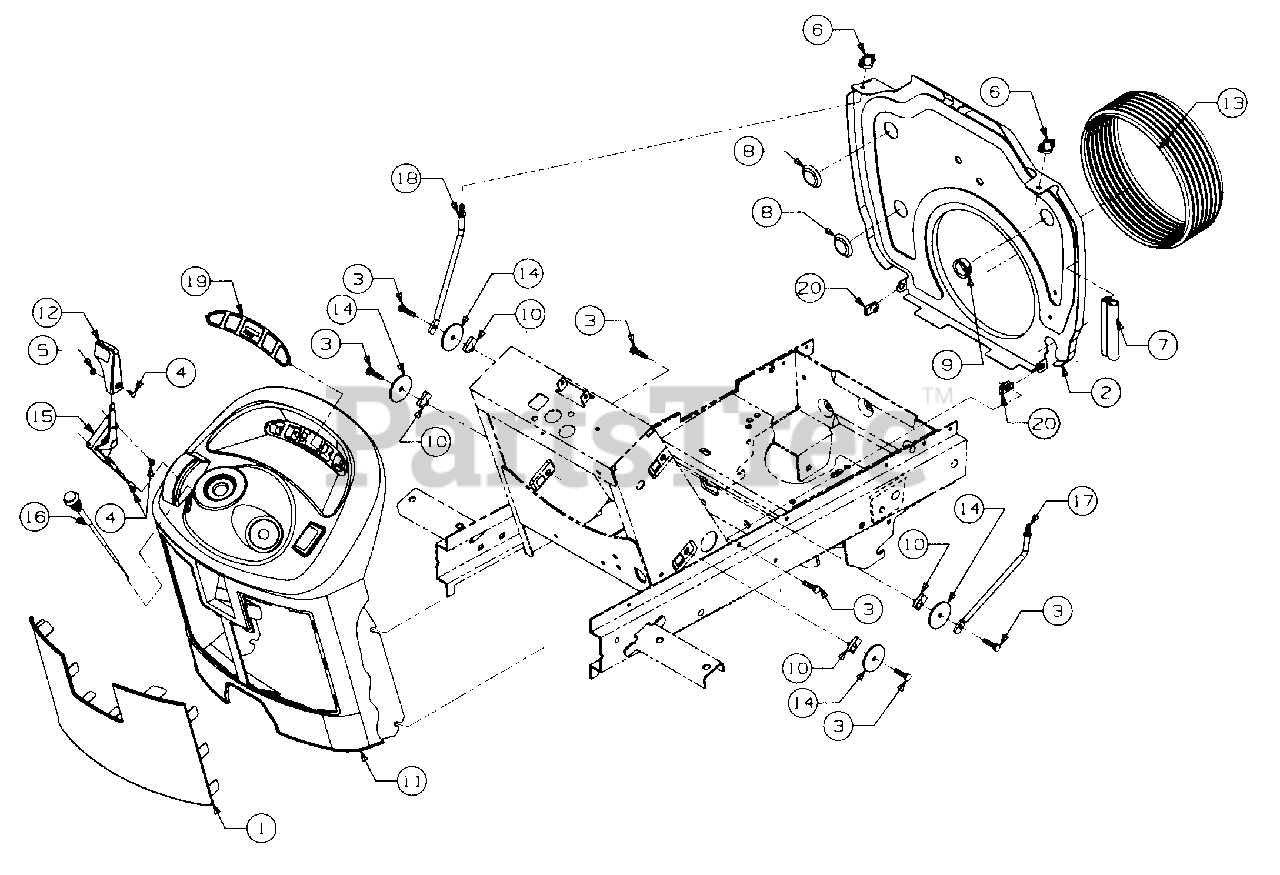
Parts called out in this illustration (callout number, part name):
2	Bulkhead, Lower
3	Screw, Hex Cap, 1/4-20 x 1.0 Lg GR2
4	Screw, Cross Rec Truss Hd #8-32 x .38 Lg
5	Nut, #8-32
6	Nut, Wing w/Bell Washer, 1/4-20
7	Seal, Push-on Trim, 14" Lg
8	Plug, Button, 1.12 Dia
9	Bushing, Snap, 7/8 ID
10	Nut, U-Clip, 1/4-20
11	Panel, Dash
12	Knob, Throttle
13	Boot, Intake
14	Washer, Flat, .285 x 1.75 x .10 Thk
15	Control, Throttle
16	Control, Choke
17	Rod, RH Mounting
18	Rod, LH Mounting
19	Label, Dash
20	Nut, U-Type Speed, 1/4-20
